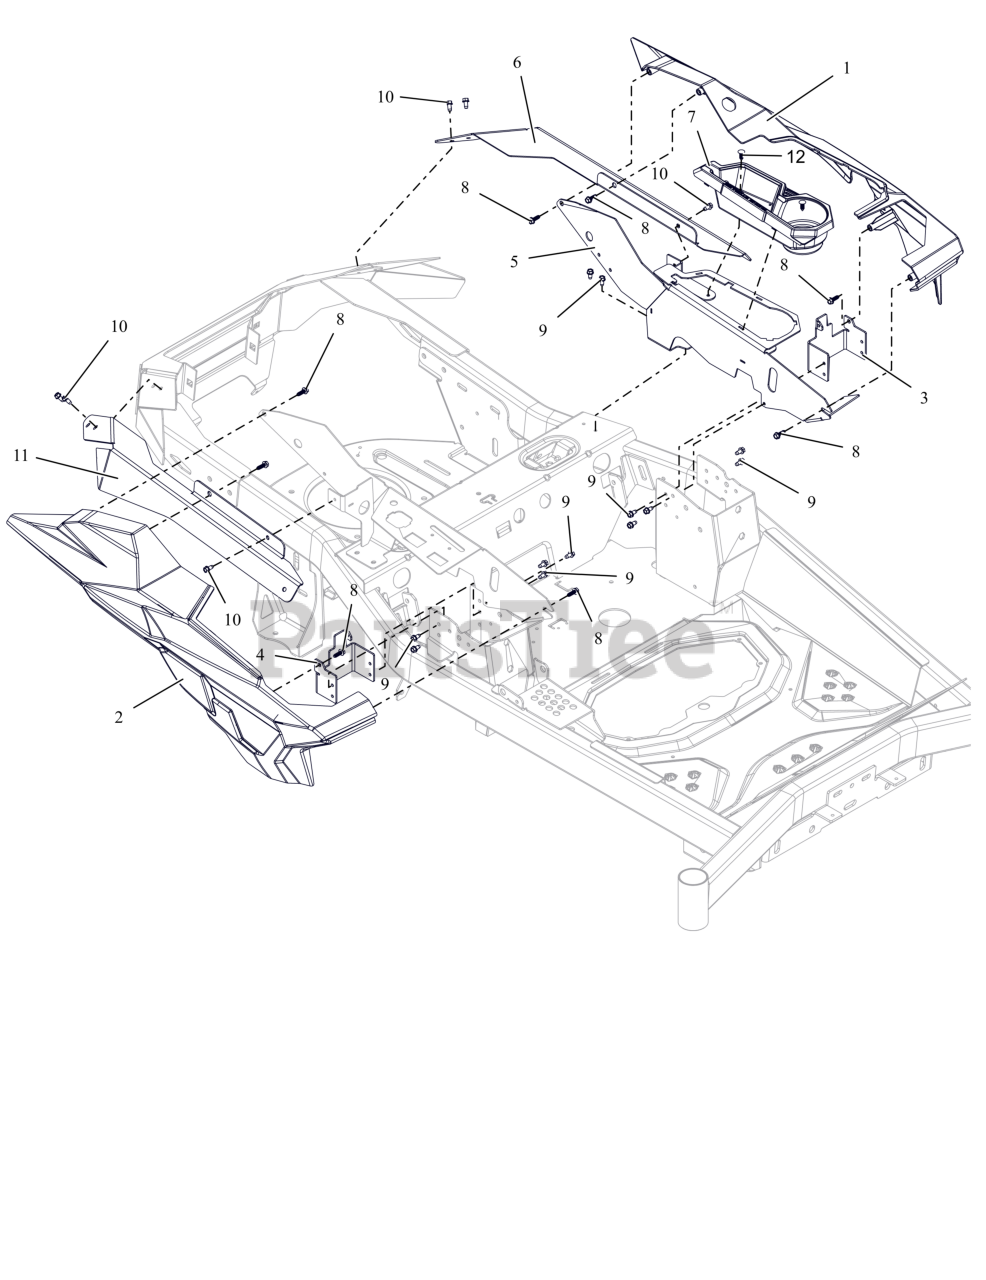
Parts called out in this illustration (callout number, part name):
1	KIT-LH GRAVELY FENDER W/ DECAL
2	FENDER- RH-GRAVELY
3	BRKT, FRONT FENDER MOUNT(LH) (BLACK)
4	BRKT, FRONT FENDER MOUNT(RH) (BLACK)
5	PANEL- CONTROL-LH-GRAVELY
6	BRKT- FENDER MOUNT-LH
7	HOLDER- CUP - GRAVELY
8	SCR, PLASTITE-HWH 0.25 X 0.75 ZC120
9	SCR-TAP .25-20X.50 HWH ZCC
10	SCR-TAP .25X.50 HWH ZB500
11	BRKT- FENDER MOUNT-RH
12	RIVET, .25 NYLON PANEL
